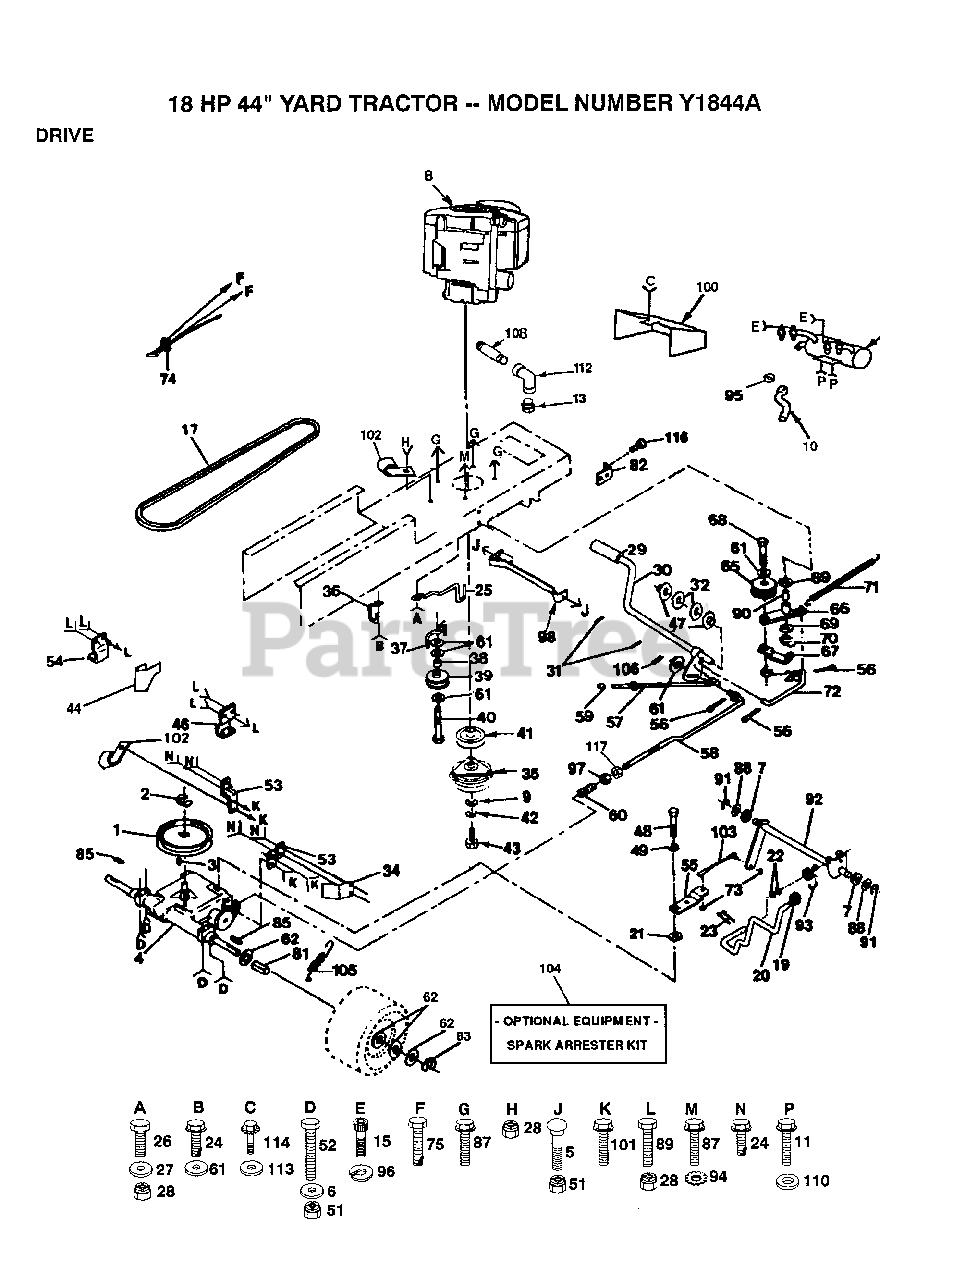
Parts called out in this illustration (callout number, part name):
1	PULLEY TRANSAXLE
2	RING
4	TRANSAXLE PEERLESS MODEL NO
5	BOLT
6	WASHER
7	BUSHING
9	WASHER
15	SCREW
17	BELT.GRDRV.94.75
19	KNOB.DUCKHEAD.1/2
21	WASH-SHFT PLT LT
22	WASHER
23	PIN COTTER 1/8
24	SCREW
25	KEEPER.BELT.ENG.L
26	BOLT
27	WASHER
29	PEDAL COVER T
32	WASHER LT
34	"KEEPER,BELT RH"
36	RETAINER BELT
37	BELT KEEPER LT
38	SPACER T
39	PULLEY.IDLER.FLAT
40	BOLT
42	LOCKWASHER
44	KEEPER BELT LH
46	BRKT TRANS RH
47	NYLON BEARING
49	WASHER PM
52	BOLT HEX
53	STRAP TORQUE
54	BRKT TRANS LH
55	"ARM,SHIFT"
56	COTTER PIN
57	BRAKE PARK ROD
58	ROD BRAKE
59	PLUNGER CAP T
60	"SPRING,ROD BRAKE"
61	WASHER
62	WASHER
66	ARM IDLER
67	RETAIN BELT
69	WASHER LT
70	KLIP RING
71	"SPRING, RETURN LT"
72	"LINK, CLUTCH T"
73	NUT 1/4-28
75	SCREW LT
81	SPACER HYT
82	BRACKET LT
83	E RING HYT
85	SQ KEY STD
87	SCREW LT
88	WASHER D
90	"LY, BEARING"
92	"SHAFT,SHIFTER"
93	"SPRING,TORSION"
94	LOCKWASHER
95	MUFFLER CLAMP
96	LOCKWASHER
97	NUT
101	SCREW
102	CLIP T
103	"ROD,TIE "
106	CLIP HAIR PIN
108	PIPE NIPPLE LT
109	WASHER PM
110	LOCKWASHER
112	ELBOW
116	SCREW
117	NUT
